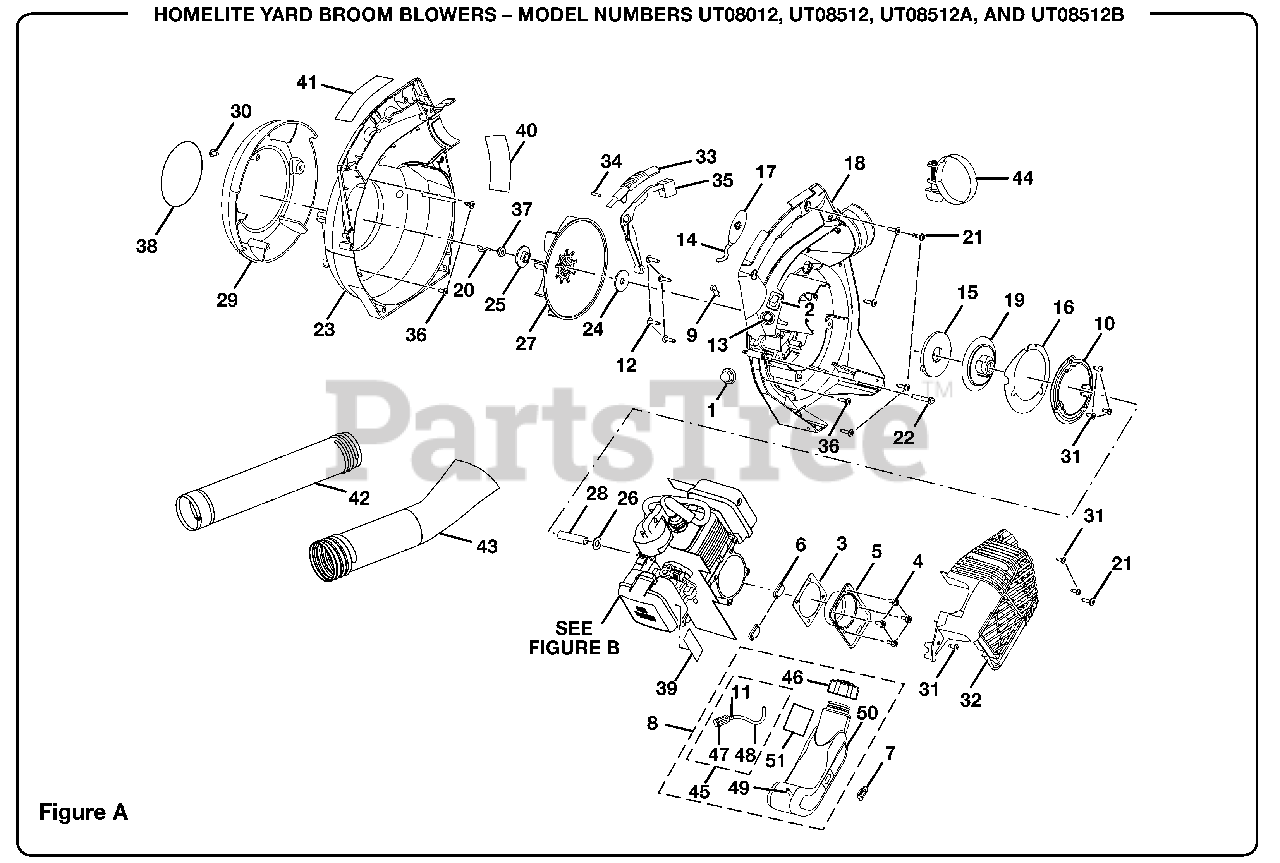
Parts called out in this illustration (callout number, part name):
1	PRIMER BULB
2	SWITCH
3	CRANKCASE GASKET
4	SCREW (10-24 x 9/16 in. PAN HD.)
5	CRANKCASE COVER
6	RUBBER BUMPER
7	BIG BUMPER
8	FUEL TANK ASSEMBLY
9	BUSHING - STARTER ROPE
10	BAFFLE PLATE
11	WIRE CLAMP
12	SCREW (10-24 x 3/4 in. TRUSS HD.)
13	BUSHING STARTER
14	STARTER ROPE
15	SPRING & CONTAINER
16	BAFFLE GASKET
17	STARTER GRIP
18	INNER VOLUTE HOUSING
19	PULLEY ASSEMBLY
20	WIRE LOOP
21	SCREW (10-14 x 3/4 in. TORX TRUSS HD.)
22	SCREW (10 x 1-5/8 in. HEX HD.)
23	OUTER VOLUTE
24	FLAT WASHER
25	FAN ADAPTOR
26	FLAT WASHER
27	FAN
28	FAN SPACER
30	SCREW (1/4-20 x 3/4)
31	SCREW (#8 x 1/2 in. PAN HD.)
32	BLOWER SHROUD
36	SCREW (10-24 x 3/4 in. TORX TRUSS HD.)
37	LOCK NUT (3/8-24)
38	DOOR LABEL (YARD BROOM)
39	CHOKE LABEL
40	FAN INTAKE WARNING LABEL
41	WARNING/STARTING LABEL
42	UPPER TUBE
43	LOWER NOZZLE
45	FUEL FILTER KIT
46	FUEL CAP ASSEMBLY
47	FUEL FILTER
48	RUBBER TUBING (165.10 mm)
49	RUBBER TUBING (196.85 mm)
50	FUEL TANK
51	HEAT SHIELD
